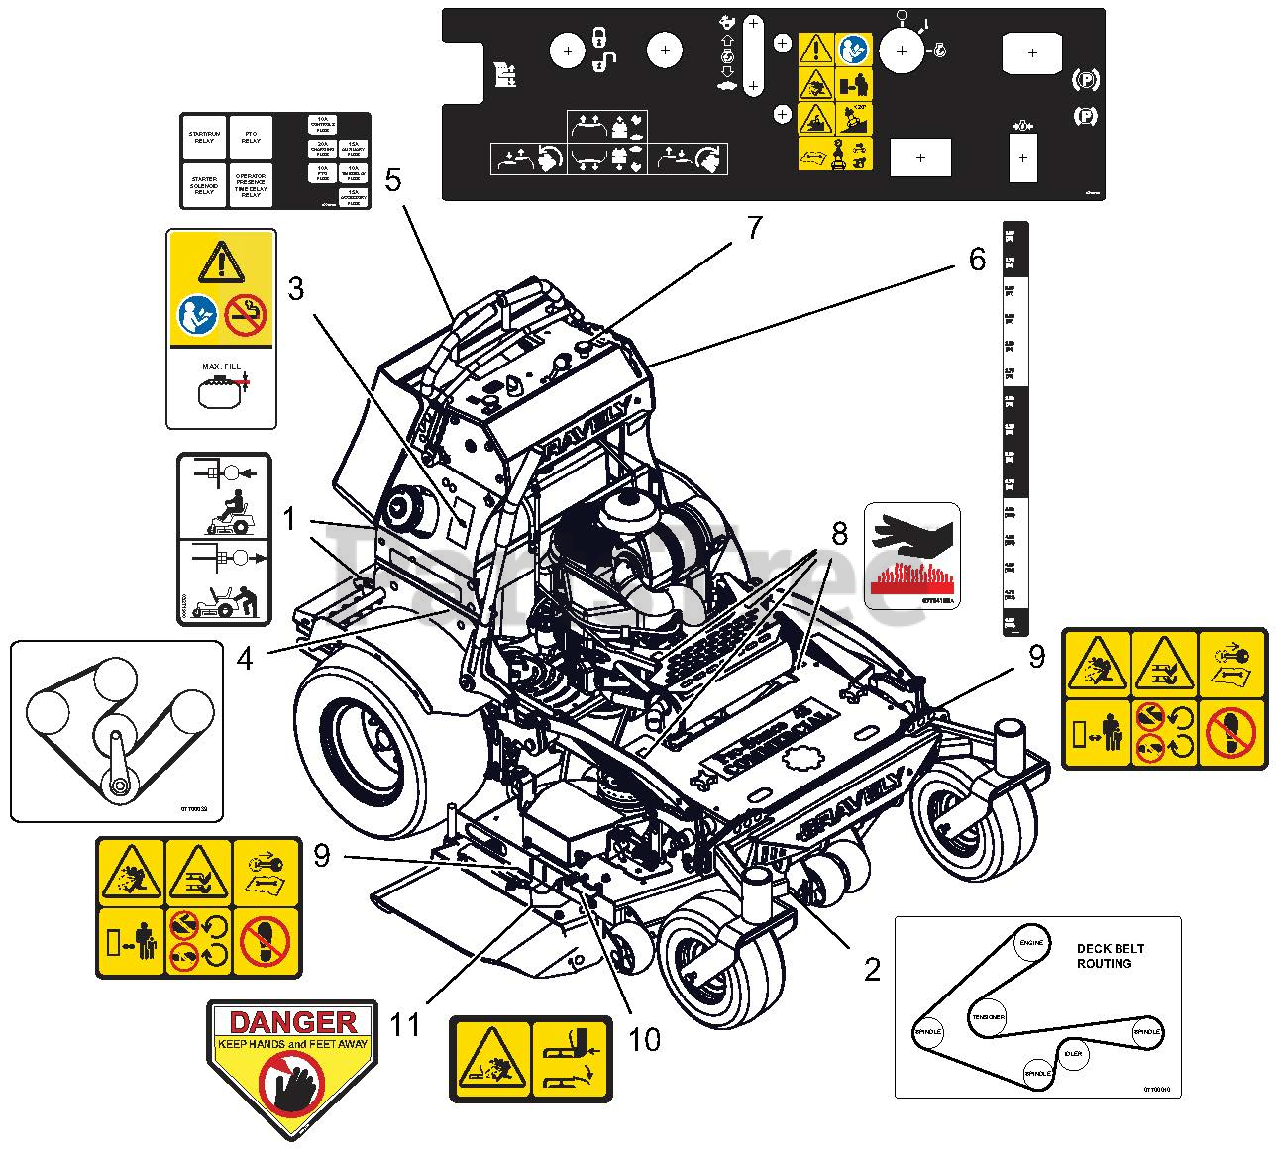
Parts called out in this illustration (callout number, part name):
1	DECAL, TRANSMISSION DISCONNECT
2	DECAL, BELT ROUTING 48/52 REV
3	DECAL, FUEL Warning
4	DECAL, HYDRO BELT
5	DECAL, FUSE BLOCK
6	DECAL, HEIGHT OF CUT - PROSTANCE
7	DECAL, CONTROL PANEL
8	DECAL HOT SURFACE
9	DECAL, SAFETY - MOWER DECK
10	DECAL, SAFETY - DECK GUARDING
11	DECAL, DANGER
